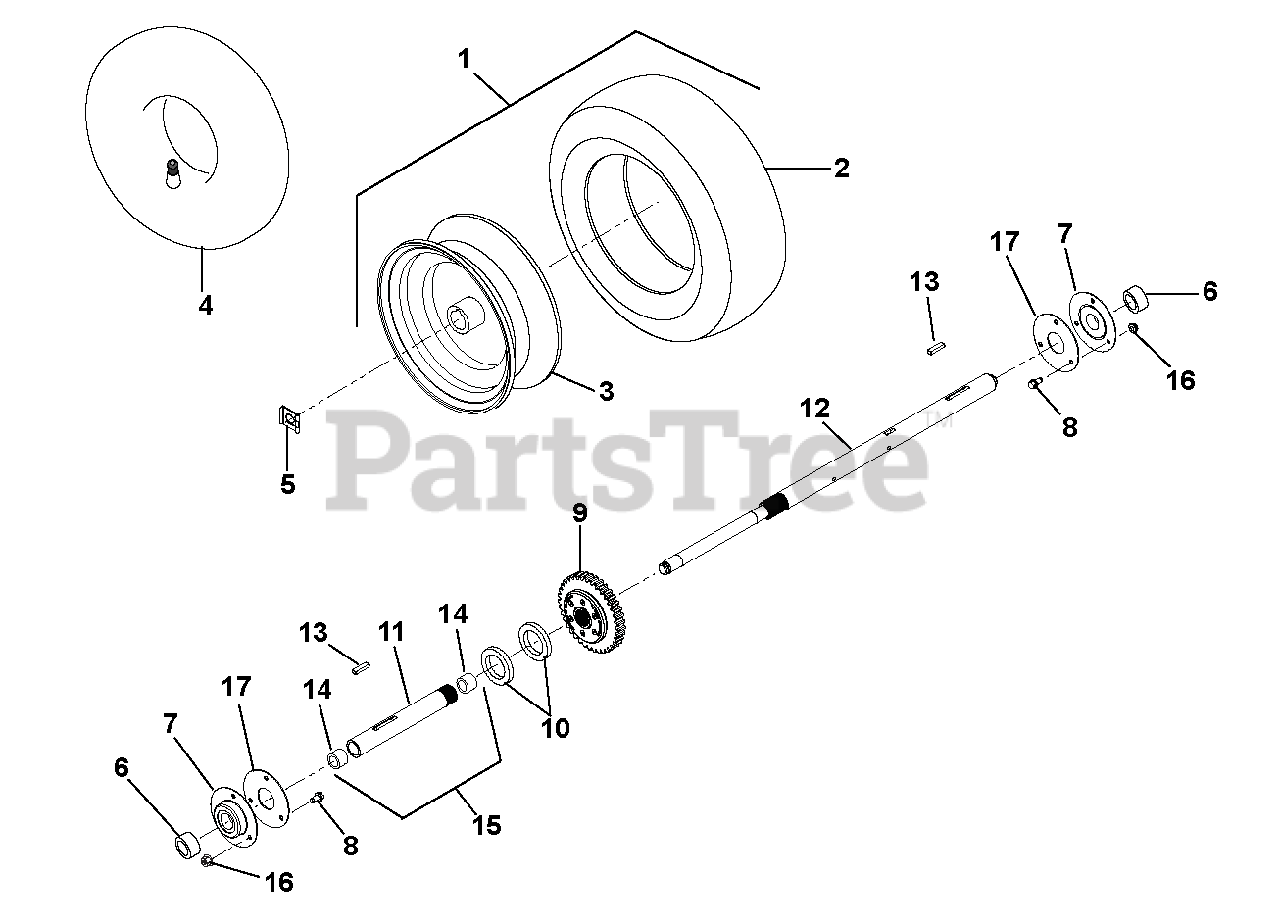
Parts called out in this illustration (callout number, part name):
1	TIRE/WHEEL,RH 16X4.8-8 DIFF T2
2	TIRE, 4.80-8 K478
3	HUB, WHEEL - 16X4.8-8 DIFF
4	TUBE
5	CLIP, SNAP .625 DIA
6	SPACER, PRO AXLE BEARING
7	BRG-FLG 1.003/1.000 3 BOLT
8	@BLT-HEX .25-20X.75 GR5 YWZC
9	DIFFERENTIAL, AUTOMATIC
10	WSHR-FL-STL- 1.062X2.0X.134 YZ
11	AXLE, SHORT-PRO AUTO DIFF
12	AXLE, LONG-PRO AUTO DIFF
13	KEY-RECT .25X.188X1.00
14	BSHG-SLV .706X.764X.75 BRZ
15	AXLE, SHORT-AUTO W/BUSHINGS
16	@NUT-LK-TOP-FLG .25-20 YWZC
17	PLATE, BEARING SPACER
